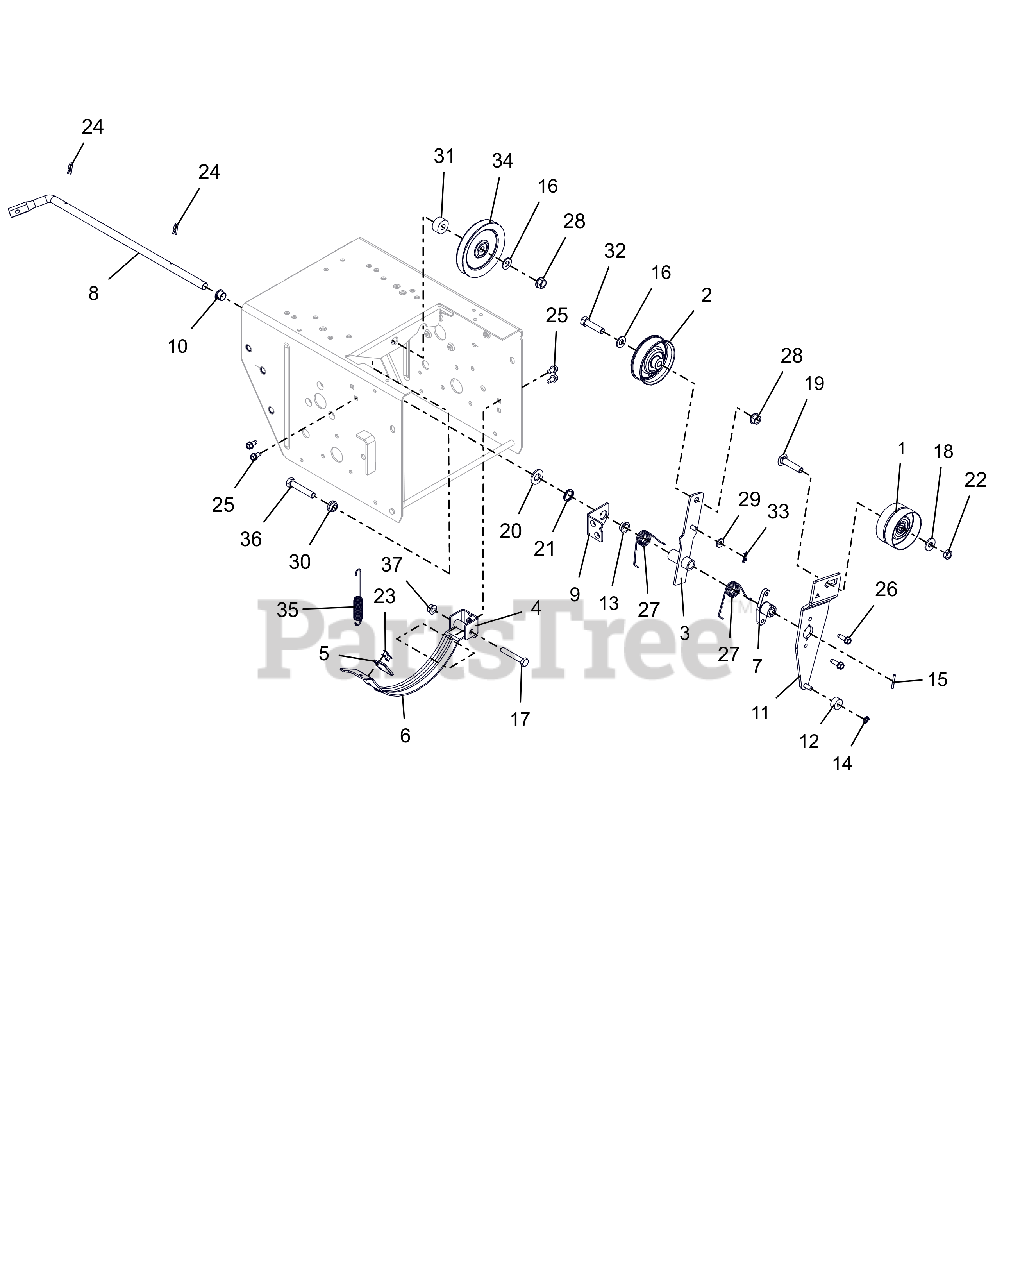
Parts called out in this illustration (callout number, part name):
1	IDLER, FLAT-2.75 OD X .375 ID
2	IDLER, FLAT - 3.05" X .75"
3	ARM, TRACTION CLUTCH
4	PIVOT, BRAKE
5	PAD, BRAKE
6	ARM, BRAKE-ATTACHMENT
7	HUB, BRAKE ARM
8	ARM, ATTACHMENT
9	BRACKET, SUPPORT
10	BUSHING, POLYLINER-.50 SPLIT
11	ARM, IDLER-ATTACHMENT
12	BSHG,SLV .265 X .625 X .375
13	BSHG,FLANGE .500X.625X.270X.75
14	RG-RTNG-EXT .250X.010
15	PIN-ROLL .125X1.00
16	WSHR,FLT .406X.812X.065 ZCC
17	BLT, HEX .31-18X2.00 G5 ZCC
18	WSHR,FLT .375X.875X.083 ZCC
19	BLT, RHSSN .38-16X1.75 G5 ZCC
20	WSHR,FLT .531X1.062X.095 ZCC
21	WAVE SPRING .600X.875X.25FH
22	NUT-LK-CTR-JAM .375-16 GB ZCC
23	RVT, POP .1875 ZCC
24	CLIP, SPRING
25	SCR-TAP .25-20X.50 HWH ZCC
26	SCR,TAP .25-20X.75 HWH TR ZCC
27	SG-TORS .067X.88
28	NUT-LK-TOP-FLG .38-16 ZC120
29	WSHR,FLT .281X.625X.065 ZCC
30	BSHG, FLANGE .391X.56X.313X.75
31	BSHG,POCKET .391X.570X1.0X.450
32	BLT, HEX .38-16X1.50 G5 ZCC
33	PIN, HAIR #178 .06X.77 ZCC
34	SHV, .38"ID X 4.00"OD V-IDLER
35	SG-TENS .056X.60X4.40
36	BLT,HEX .38-16X2.00 G5 ZCC
37	NUT-LK-TOP-FLG .312-18 GF ZCC
